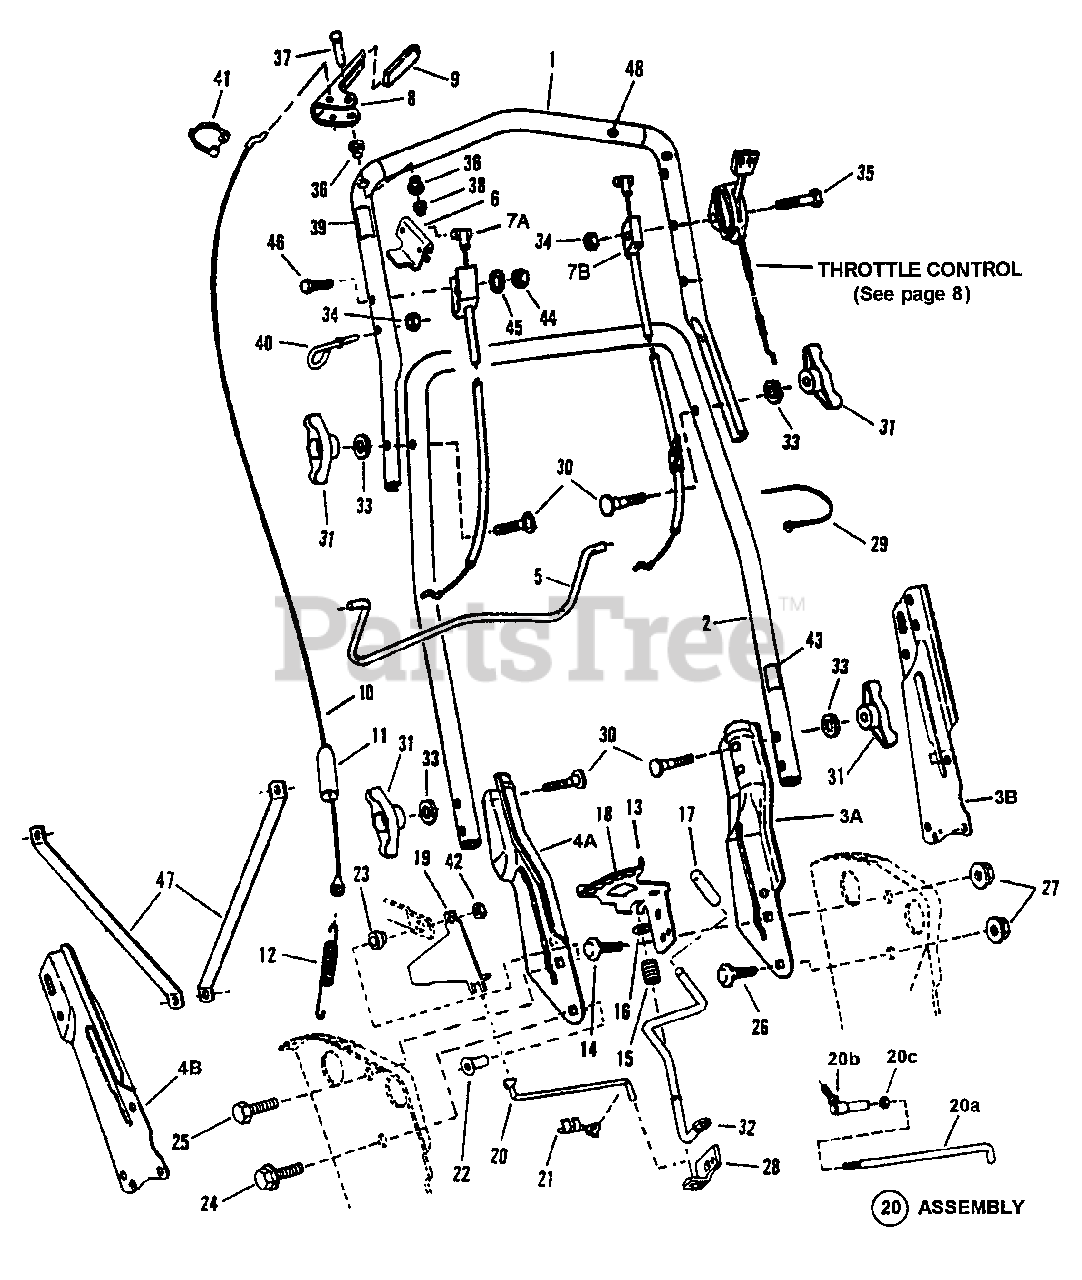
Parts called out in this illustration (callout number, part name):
1	HANDLE, Upper
2	HANDLE, Middle
3A	HANDLE, Lower Left Hand
3B	HANDLE, Lower L.H. Adjustable
4A	HANDLE, Lower Right Hand
4B	HANDLE, Lower R.H. Adjustable
5	BAIL, OPC Control (12.5" Wide)
6	CLIP, Blade Control
7A	CABLE, Blade Control (46-1/16")
7A	CABLE, Blade Control (55-3/4")
7A	CABLE, Blade Control (54-13/16")
7A	CABLE, Blade Control (49-1/4")
7B	CABLE, Blade Control (52-13/16")
8	HANDLE, Wheel Drive
9	GRIP, Wheel Drive Handle
10	CABLE, Clutch Pull (Z-Bend, 36-3/16" Long)
10	CABLE, Clutch Pull (Z-Bend, 38-5/8" Long)
10	CABLE, Clutch Pull (Z-Bend, 38-5/16" Long)
11	COVER, Vinyl
12	SPRING, Clutch
13	SECTOR, Speed
14	BOLT, 5/16 x 1" Round Head Carriage, Grade 5
15	SPRING, Speed Control
16	WASHER, 3/8" Flat
17	GRIP, Speed Control Handle
18	DECAL, Speed Select
19	GUIDE, Lower V-Belt
20	ROD, Transfer
20	ASSEMBLY, Transfer Rod
20A	LINK, Transfer
20B	BALL JOINT, 1/4-28
20C	NUT, 1/4-28 Hex
21	CLIP, Transfer Rod
22	TEE-NUT, 5/16-18
23	BUSHING, Differential
24	BOLT, 5/16-18 x 3/4" Flange Lock, Grade 5
25	SCREW, 5/16-24 x 1" Hex Cap, Grade 5
26	BOLT, 5/16-18 x 5/8" Short Neck Carriage, Grade 5
27	NUT, 5/16-18 Hex Flange Lock, Grade 5
28	BRACKET, Speed Control Rod
29	TIE, Wire
30	SCREW, 5/16-18 x 1-7/8 Curved Head, Grade 2
31	T-KNOB, 5/16-18
32	LEVER, Speed Control
33	WASHER, 5/16 Internal Tooth Lock
34	NUT, 1/4-20 Hex, Grade 5 or B (2 with Kawasaki Engine)
35	SCREW, 1/4-20 x 2" Hex Cap, Grade 5
36	BUSHING
37	PIN, Clutch Handle
38	PUSH-NUT, 1/4"
39	DECAL, Blade Control (Right Hand Side)
40	GUIDE, Rope
41	CLAMP
42	NUT, 5/16-24 Hex Center Lock, Grade 5
43	DECAL, Shift Warning
44	NUT, 1/4-20 Hex
45	WASHER, 1/4" Internal Tooth Locking
46	SCREW, 1/4-20 x 1-3/4 Hex Cap, Grade 5
47	BRACE
48	FOAM GRIP
